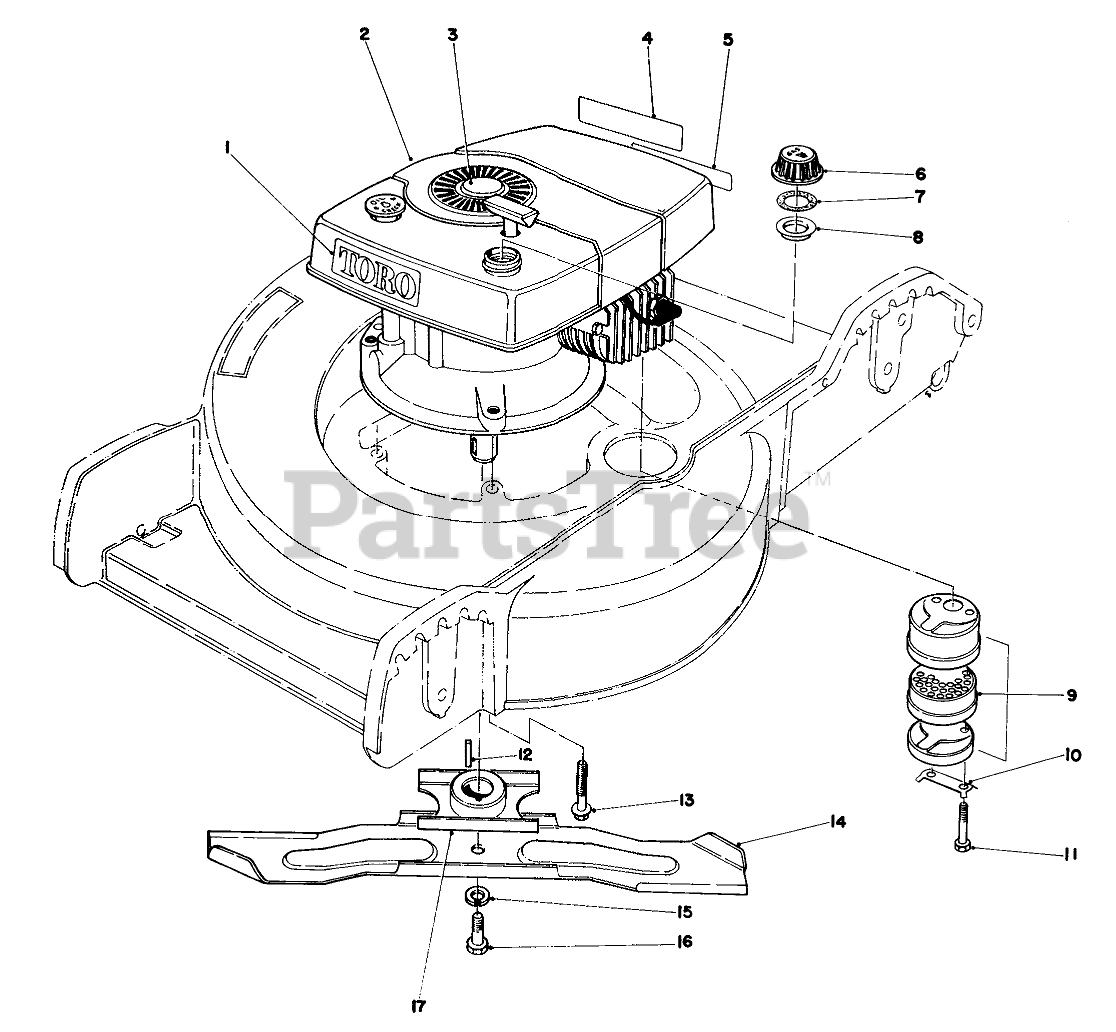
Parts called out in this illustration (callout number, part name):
1	Decal Toro
2	Engine
3	Plug Button
4	Decal Maintenance
5	Decal-Primer Bulb
6	Gas Cap (Incl. Ref. #7 & 8)
7	GASKET
8	GAS CAP BAFFLE
9	Muffer Assy. (Incl. Ref. #10 & 11)
10	CLIP - LOCKING
11	SCREW-HH
12	KEY-SQUARE
13	3/8-16 X 2 CAPSCREW
14	Blade
15	WASHER-LOCK
16	SPECIAL SCREW
17	Blade Retailer
